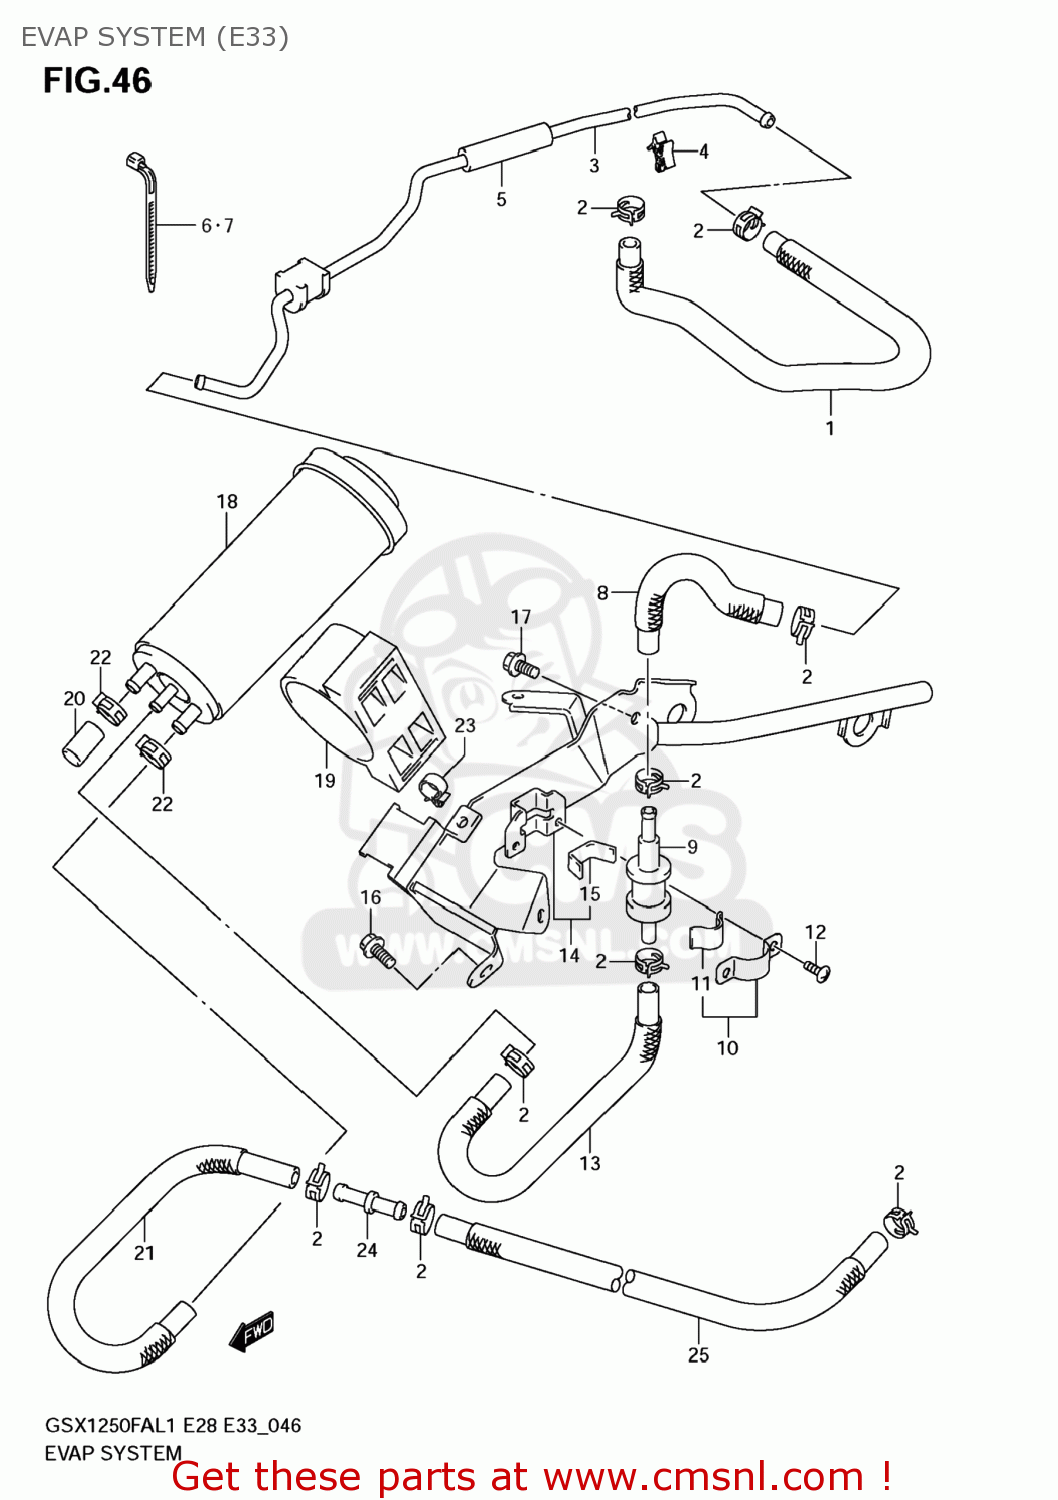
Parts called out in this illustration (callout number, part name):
1	HOSE,TANK & BREATHER VALVE
2	CLIP
3	PIPE,TANK & BREATHER
4	CLAMP
5	CUSHION,FR FENDER SIDE
6	CLAMP(L:145)
7	CLAMP(L:95)
8	HOSE,TANK & BRTHR VALVE NO.2
9	VALVE,FUEL TANK BREATHER
10	PLATE,FUEL TANK BREATHER NO.2
11	CUSHION
12	SCREW
13	HOSE,CSTR & BREATHER VALVE
14	BRACKET,CANISTER
15	CUSHION
16	BOLT
17	BOLT
18	CANISTER SET
19	CUSHION,CANISTER
20	CAP,OD:11.5
21	HOSE,CSTR & PURGE VALVE
22	CLIP
23	CLAMP
24	JOINT
25	HOSE,CSTR & PURGE VALVE NO.2
